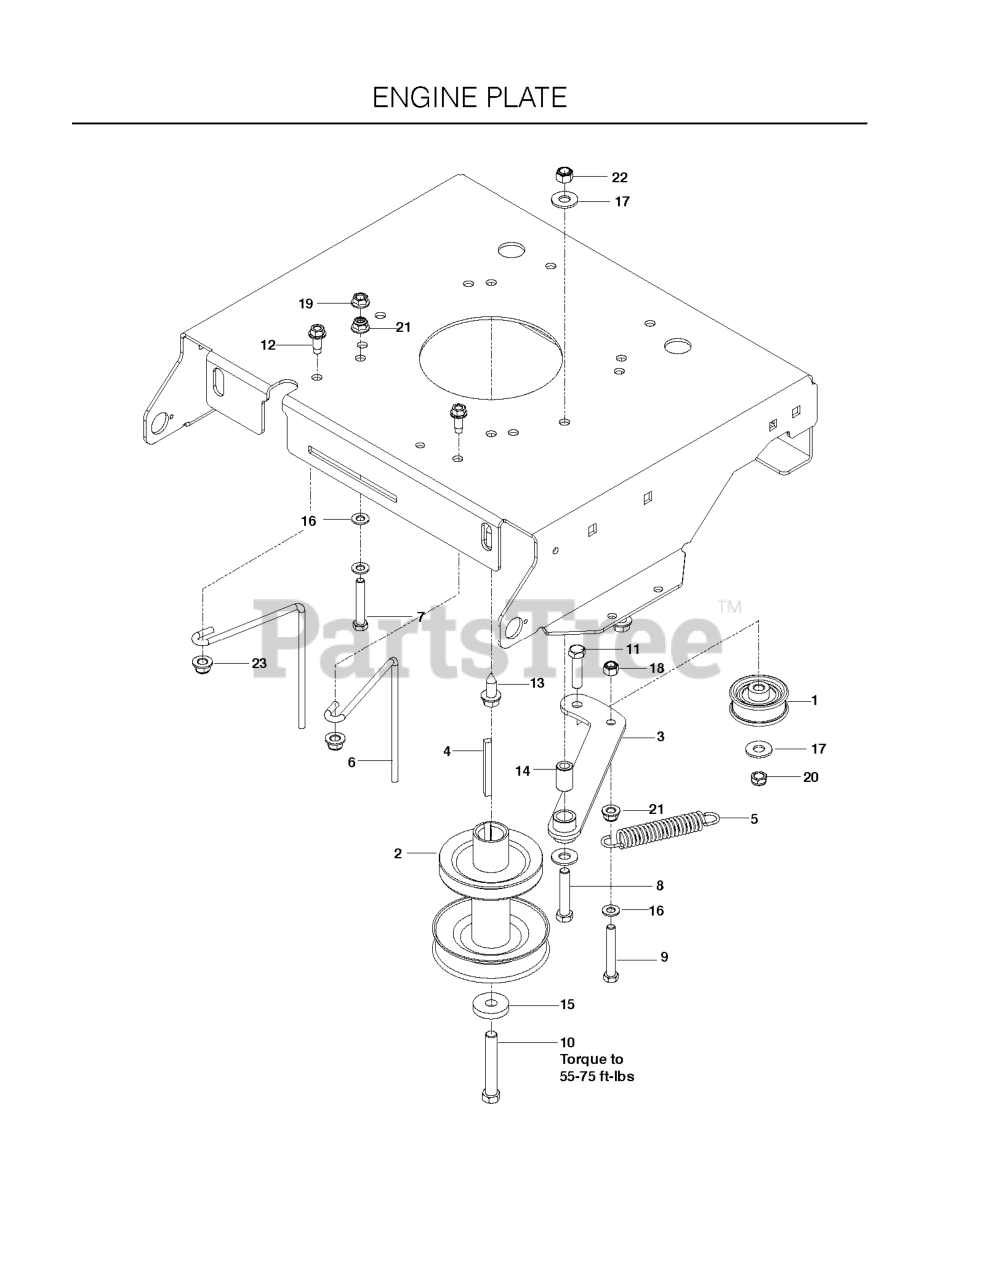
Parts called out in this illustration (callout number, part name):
1	PULLEY IDLER
2	PULLEY, ENGINE 30"
3	IDLER WLDT.
4	KEY 1/4 SQ X 2-1/2
5	SPRING - 3.50
6	BELT GUIDE
7	HCS 5/16-18X2
8	HCS 3/8C X 2
10	HCS 7/16-20 X 2-3/4
11	HCS 3/8C X 1 1/2
12	HCS 3/8C X 1 1/4 GR5
13	HHFS 3/8-16 X 1.0 THD FORMING
15	WASHER .43X1.38X.25
16	FLAT WASHER 5/16 SAE
17	WASHER 3/8 FLAT
18	NUT 5/16 NYLOC
19	NUT 5/16C WHIZ
20	NUT HEX 3/8-16 NYLON, THIN
21	5/16-18 NYLOC FLANGE NUT
22	NUT 3/8-16 NYLOC
23	NUT 3/8-16 HEX FLG NYLOC ZD
